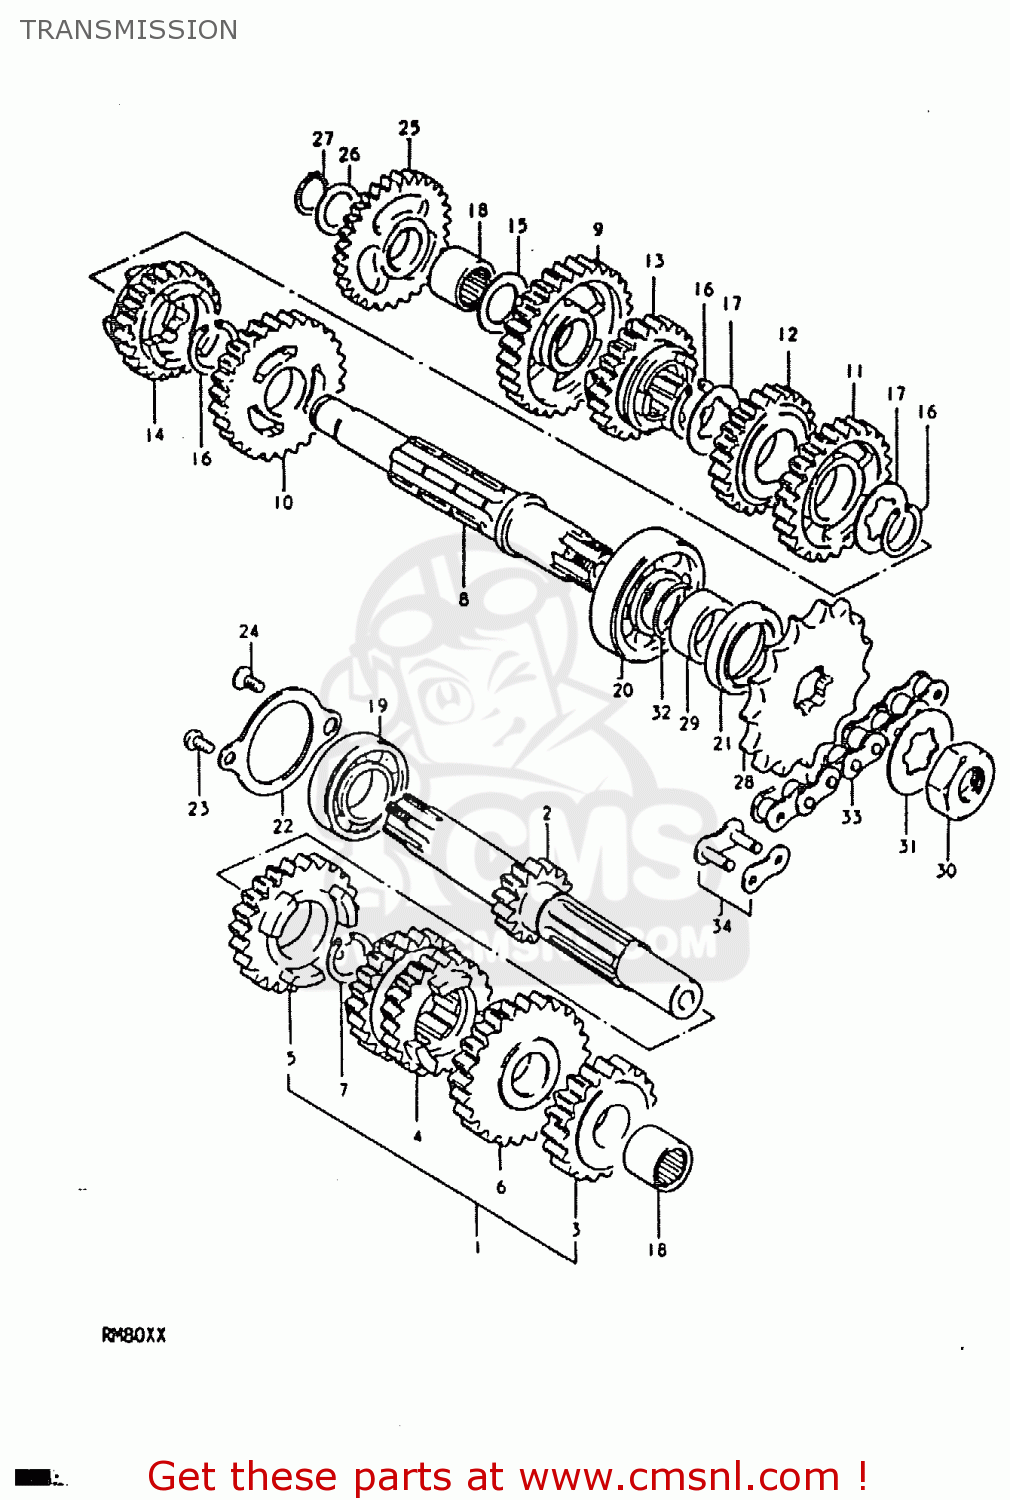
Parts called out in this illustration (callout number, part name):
1	SHAFT,COUNTER
2	SHAFT,COUNTER
3	GEAR,SECOND DRIVE
4	GEAR,THIRD/FOURTH DRIVE
5	GEAR,FIFTH DRIVE
6	GEAR,SIXTH DRIVE
7	CIRCLIP
8	SHAFT,DRIVE
9	GEAR,FIRST DRIVEN
10	GEAR,SECOND DRIVEN
11	GEAR,THIRD DRIVEN
12	GEAR,FOURTH DRIVEN
13	GEAR,4TH DRIVEN(NT:36)
14	GEAR,SIXTH DRIVEN
15	WASHER(13X24X1)
16	CIRCLIP
17	WASHER,LOCK
18	ROLLER BEARING (13X19X1
19	BEARING
20	BEARING
21	SEAL,OIL(21X35X5)
22	RETAINER,CNTR SHAFT BEARING
23	SCREW
24	SCREW
25	GEAR,KICK STARTER IDLE
26	WASHER
27	CIRCLIP
28	SPROCKET,ENGINE
29	SPACER (17X21X11)
30	NUT
31	WASHER,LOCK
32	O RING(D:1,ID:16.8)
33	CHAIN ASSEMBLY,DRIVE
34	JOINT ASSEMBLY,CHAIN
